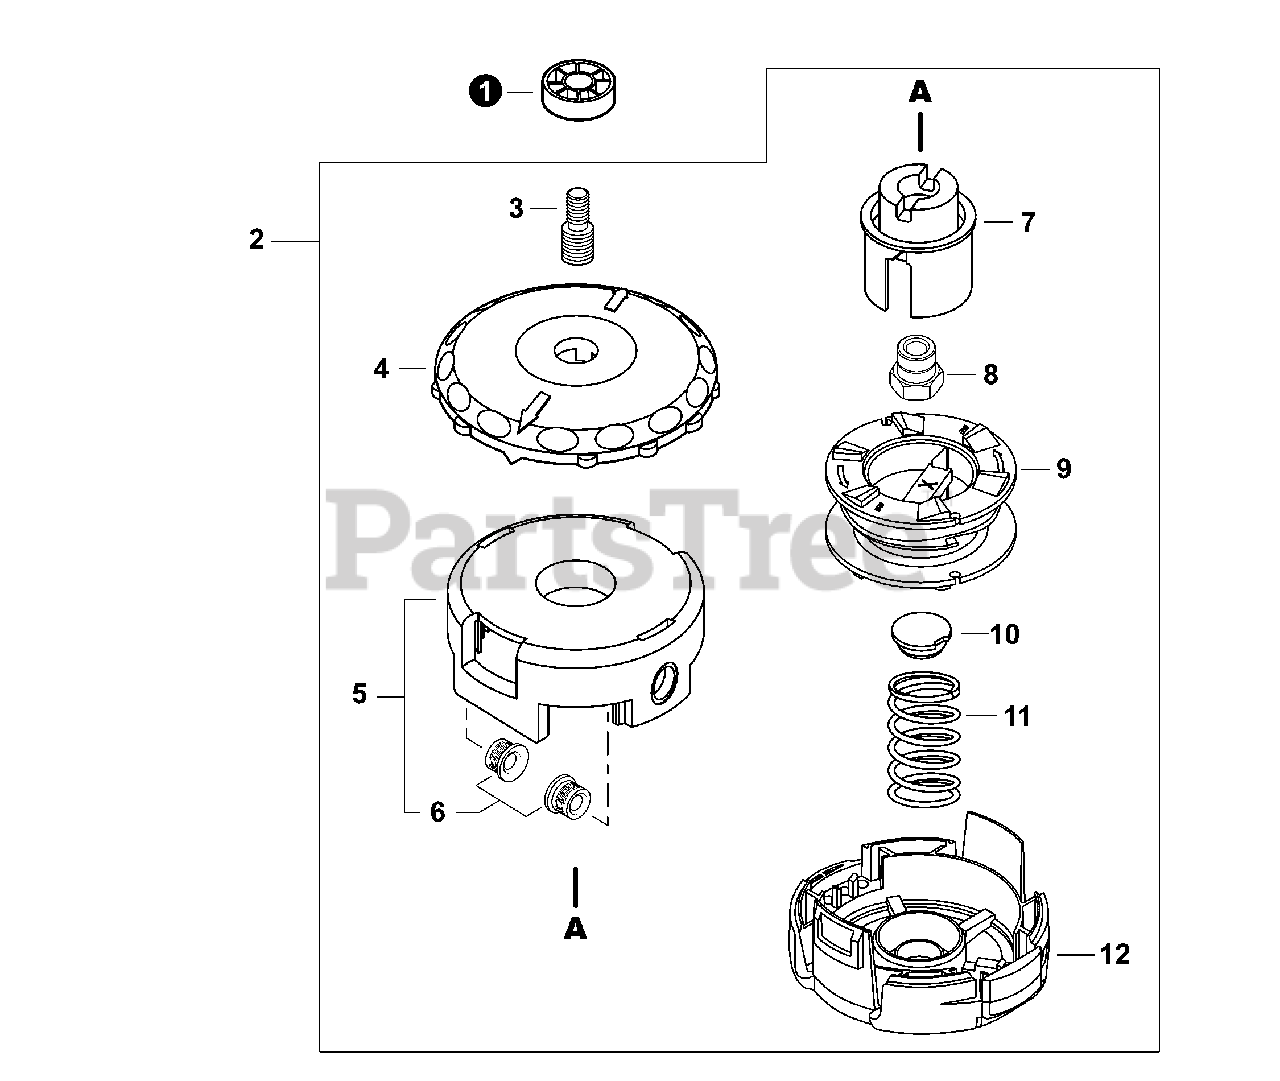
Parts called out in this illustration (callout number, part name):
1	SPACER, BLACK
2	TRIMMER HEAD, SPEED-FEED® 400
3	BOLT, STUD M7×1.00 /M10×1.25 LH GOLD
5	HOUSING ASSY, SPOOL
7	HUB (LH) BLACK
8	BUSHING M10×1.25 LH GOLD
10	CAP, SPRING
11	SPRING, GOLD
12	COVER, SPOOL
